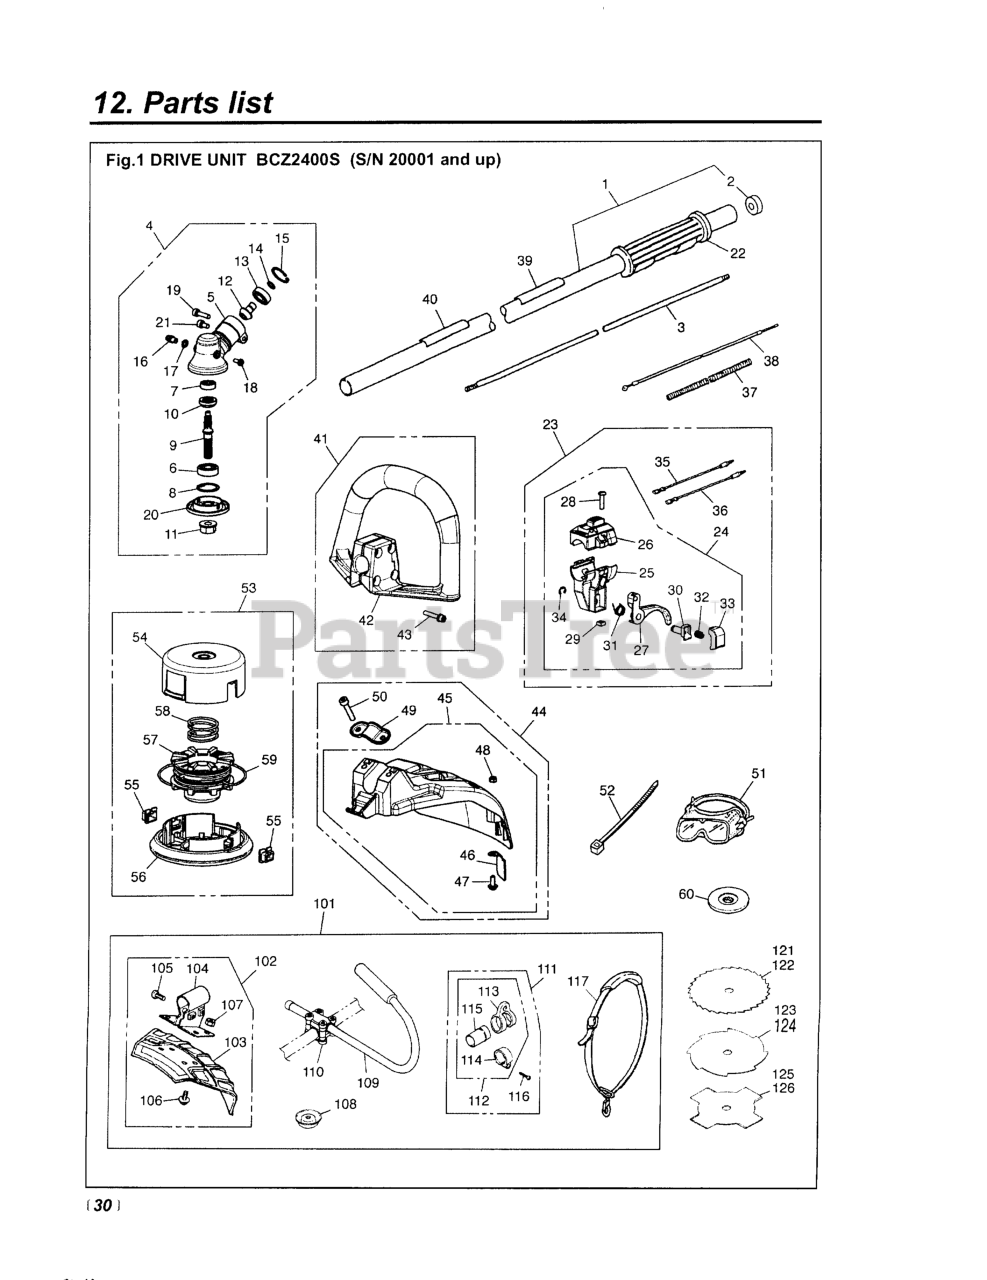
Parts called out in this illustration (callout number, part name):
1	PIPE COMP
2	SEAL
3	SHAFT (RPLS -12212)
4	GEARCASE ASSY.
5	GEARCASE
6	BEARING
7	BEARING (RPLS T3300-13521)
8	RING, SNAP, M26 X 1.2
9	SHAFT
10	GEAR
11	NUT
12	PINION
13	BEARING (RPLS T3300-13531)
14	RING, SNAP (RPLS T3300-13330)
15	RING, SNAP, M24 x 1.2
16	FITTING, GREASE
17	WASHER, M6 X .8
19	BOLT (RPLS 2850-14220)
20	HOLDER (A)
21	BOLT
22	GRIP (RPLS 3577-32140 & 3220-
24	LEVER (USE 848-8R2-0313)
26	COVER (USE 848-8RA-0340)
27	FLEX, TRIGGER
35	CORD (A), BLACK
36	CORD (B), RED
37	TUBE
38	CABLE COMP (RPLS 1633-83100)
39	PLATE, NAME
40	PLATE, CAUTION
41	HANDLE ASSY. (REPLACES -14001)
42	HANDLE T
43	SCREW
44	GUARD ASSY. (RPLS -24002)
45	GUARD COMP.
46	BLADE (RPLS T3002-24120)
47	SCREW TORX
48	NUT
49	CLAMP (REPLACES 5807-24120)
50	BOLT, TORX
51	GOGGLE
53	TAP HEAD COMP.
54	CASE (REPLACES -15111)
55	EYELET
56	COVER (REPLACES -15131)
57	HOLDER, CORD (REPLACES-15141)
58	SPRING
59	CORD
60	HOLDER (B)
101	BLADE KIT (BC00090)
102	GUARD ASSY.
103	GUARD (ACC.)
105	BOLT
106	SCREW
107	NUT, M6 X 5
108	COVER
109	HANDLE, J
110	BRACKET ASSY (REPLACES -14100)
111	HANGER ASSEMBLY
112	HANGER COMPLETE
113	HANGER
114	CLAMP
115	SLEEVE
116	SCREW, M5 x 25
117	STRAP ASSY.
121	BLADE, 9
122	BLADE, 9
123	BLADE, 8
124	BLADE, 9
125	BLADE, 8
126	BLADE, 9
